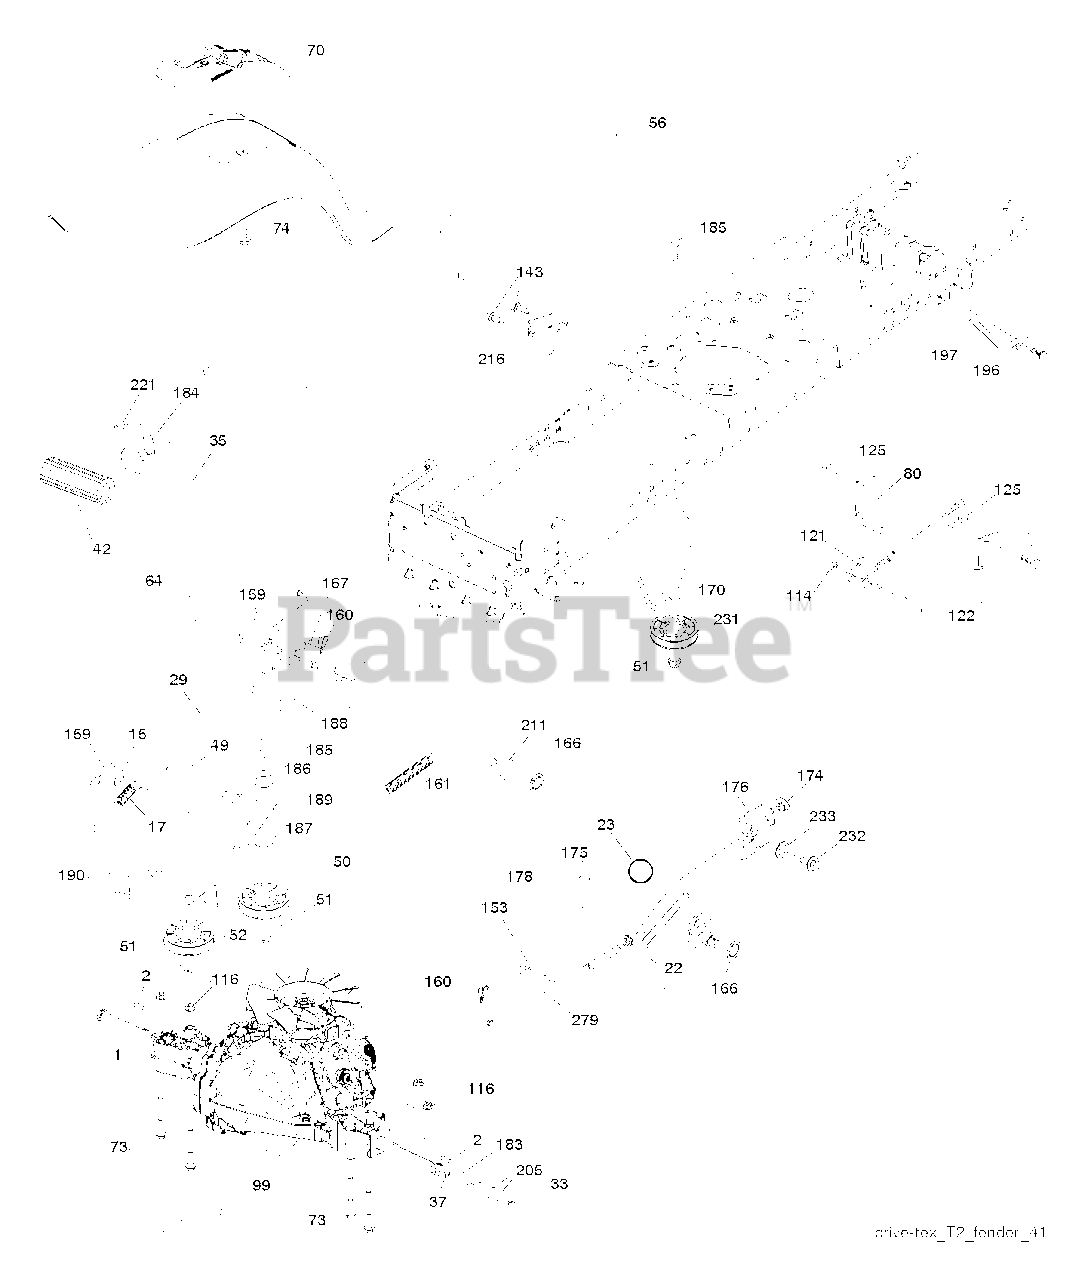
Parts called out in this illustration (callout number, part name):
2	SQUARE KEY
17	SPRING.BRAKE.HG3000/3500
22	ROD.SHIFT.FENDER.TLT.2006
23	PISTOL KNOB
29	ROD.BRAKE.T2.TEX
33	E-RING LT
35	ROD.BRAKE.PARKING.LT.T
49	BOLT
50	IDLER.FLAT.910.OFFSET
51	NUT LOCK FLG 3/8-16 UNC
52	IDLER.V-GROOVE.910.OFFSET
56	BELT.GROUND.DRIVE.T2-HP.CE
64	SHAFT.ASM.PEDAL.BRAKE.
70	CONSOLE.SHIFT.STL.HYD.BLACK
73	BOLT HEX 5/16-18 GR 5
74	SCREW.HI-LO.CONSOLE
80	STRAP.TORQUE.T2
99	ROD.ASM.BYPASS.SPRING.T2.FS
114	NUT.71038.31-18.HEX.NYLOCK
116	NUT LOCK HEX FLANGE 5/16-18
121	BRACKET STRAP TORQUE
122	BOLT.5/16-18X2.5
125	SCREW
143	SCREW LT
159	COTTER PIN
160	RETAINER CLIP
161	SPRING, RETURN LT
166	NUT.PUSH.625
167	LATCH.BRAKE.SPRING
170	KEEPER.CENTER SPAN.1.688
174	NUT.PUSH.500.2006
175	SHAFT.ASM.SHFT.T2.TLT
176	ARM.CLEVIS.ROD.SHIFT
178	SPRING.SHIFT.GT2006
183	SPACER, AXLE PVST
184	BOOT.STEERING.LT.TEX.P/L.418
186	SPACER.RETAINER
187	WASHER 12/32X2X10GA
188	LINK.CLUTCH.GROUND.DRIVE
189	BELLCRANK.GROUND.DRIVE.TEX.
190	KEEPER.BELLCRANK.DRIVE
196	SCREW 3/8-16X1
197	Clutch Anti-Rotation Wireform
211	BUSHING.SHAFT.BRAKE.HAND
216	BRACKET.PULLEY.IDLER.W/TEX
221	RETAINER.SPRING.CLIP.H
231	IDLER.V-GROOVE.1.688.OFFSET
232	BOLT FIN HEX 7/16-14 X 1
233	WASHER SERRATED
279	LINK.SHIFT.T2
